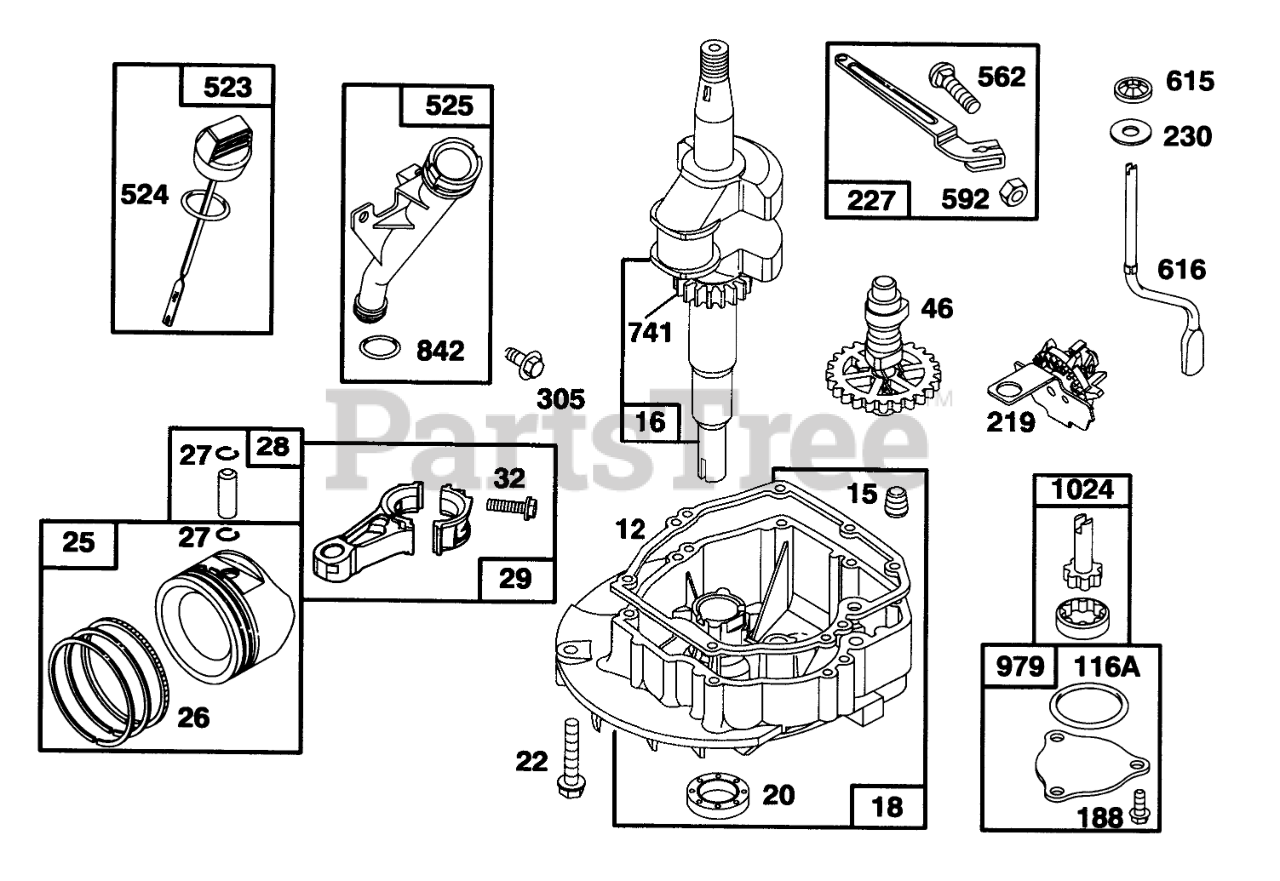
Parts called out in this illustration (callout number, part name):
12	ENGINE BASE GASKET
15	PLUG - PIPE
16	CRANKSHAFT
18	ENGINE SUMP
20	SEAL-OIL
22	SCREW - ENGINE BASE
25	STD PISTON ASSEMBLY
26	STD RING SET
27	PISTON PIN LOCK
28	PIN ASM - PISTON
29	CONNECTING ROD
32	SCREW - CONNECTING ROD
46	CAM GEAR
116A	O RING SEAL
188	SCREW - HEX HEAD
219	GOVERNOR/OIL SLINGER
227	GOVERNOR LEVER ASSEMBLY
230	WASHER
305	SCREW - HEX HEAD
523	DIPSTICK-OIL
524	O-RING
525	OIL FILLER TUBE
562	BOLT - GOVERNOR LEVER
592	NUT - HEX
615	FASTENER
616	GOVERNOR CRANK
741	TIMING GEAR
842	O-RING
979	OIL PUMP COVER
1024	OIL PUMP
